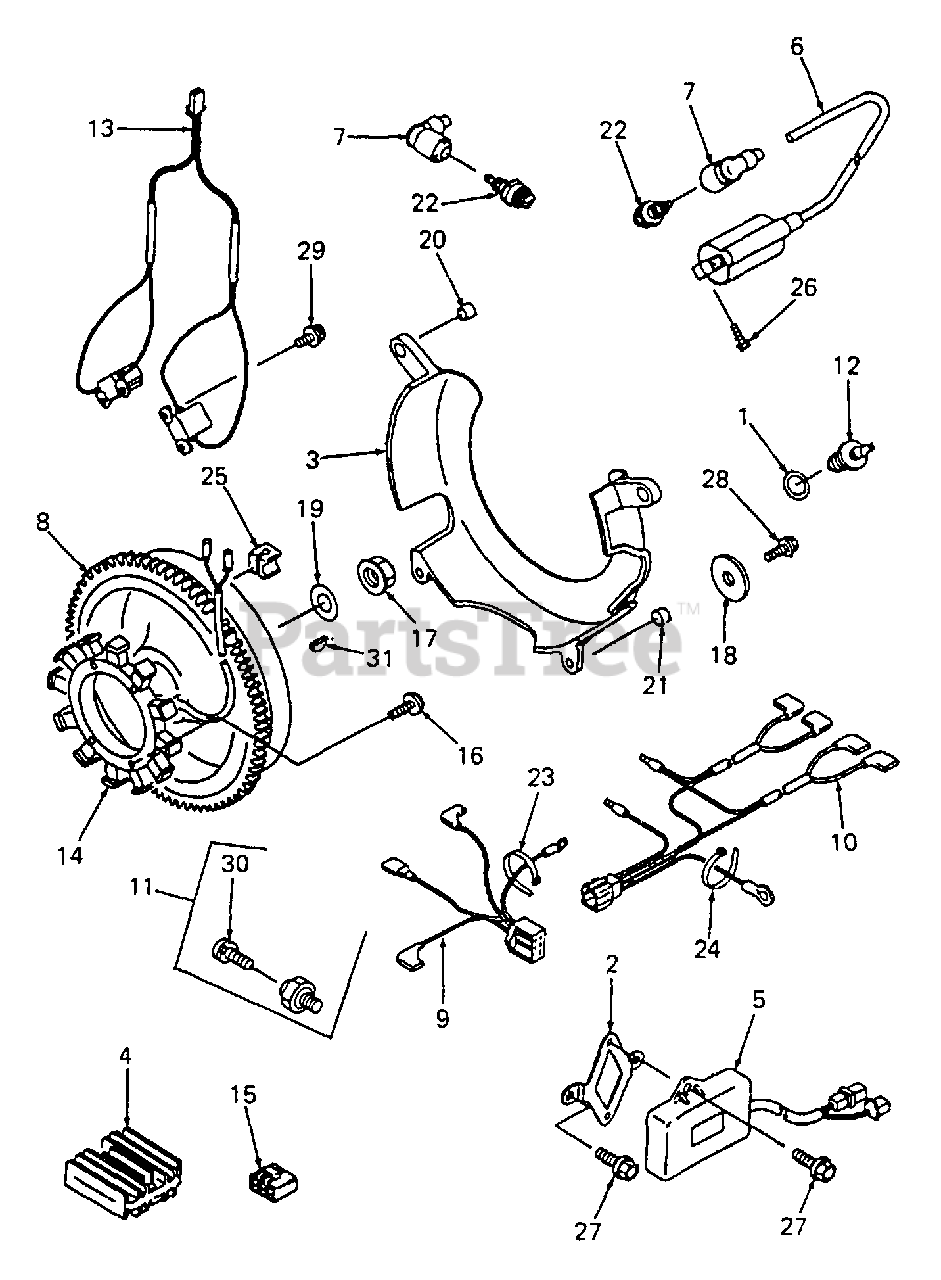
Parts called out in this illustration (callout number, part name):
1	Gasket, Prssr Switch
2	Bracket
3	Cover, Flywheel
4	Regulator, Voltage
5	Igniter
6	Coil, Ignition
7	Cap, Spark Plug
8	Flywheel Assy
11	Switch, Oil Pressure
12	Switch, Temperature
13	Coil, Pulsing
14	Coil, Charging
18	Washer, 6 x 19.5 x 2
20	Collar, 8.3 x 11.5 x 9
21	Collar, 6.2 x 7.8 x 5
22	Plug, Spark
26	Bolt, Flanged, 5 x 20
27	Bolt, Flanged, 6 x 14
28	Bolt, Flanged, 6 x 16
29	Screw, 4 x 14
30	Screw, 4 x 6
31	Key, Woodruff
